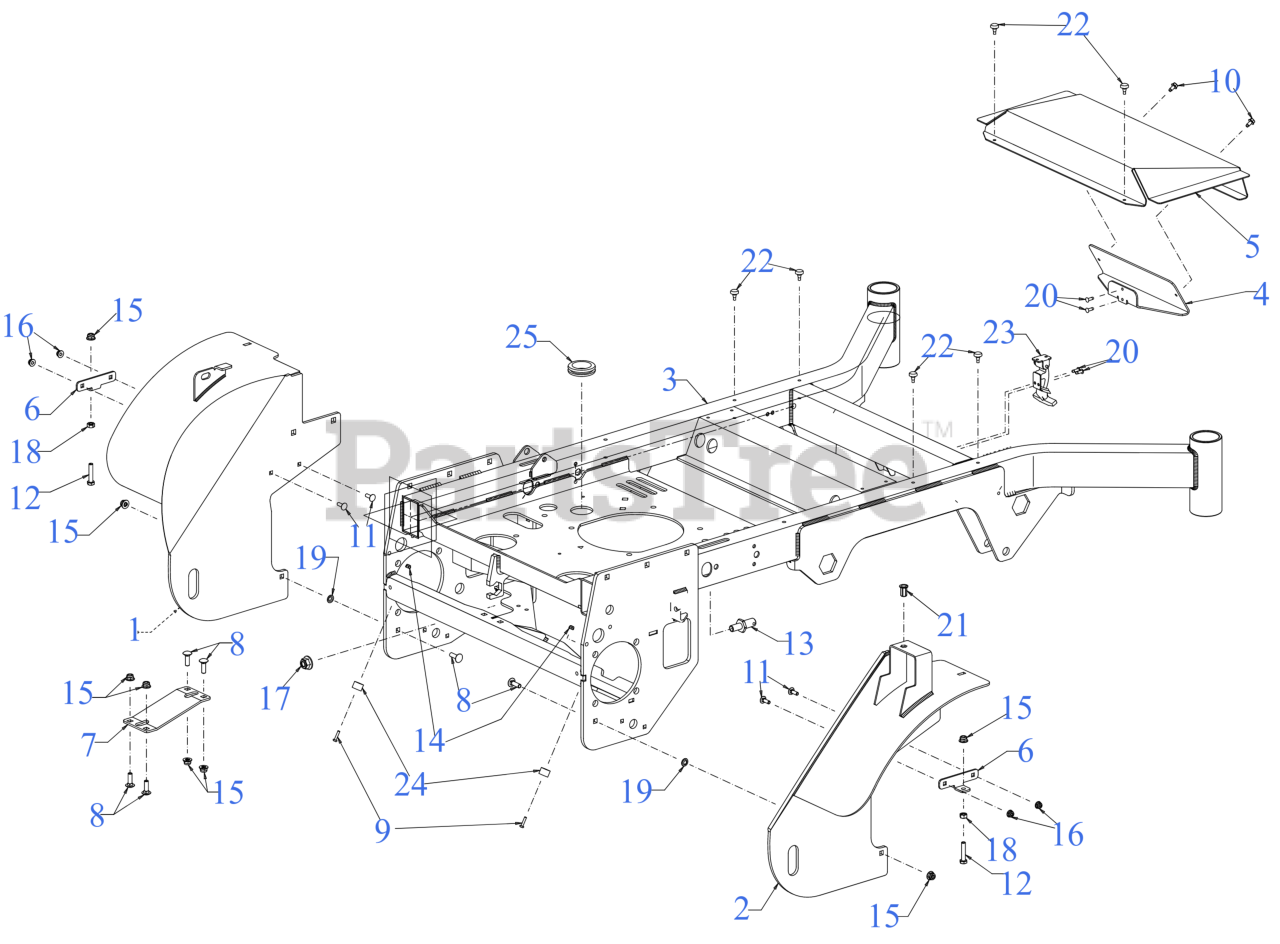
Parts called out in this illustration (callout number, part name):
1	FENDER (LH)
2	FENDER (RH)
3	60" FRAME
4	BACK PLATE
5	FRONT COVER
6	BRAKE SPRING BRACKET (RH)
7	SUPPORT BRACKET
8	CARRIAGE BOLT 5/16-18 x 1.00
9	SCREW #8-32 x .750
10	SCREW 1/4-20 X.500
11	SCREW 1/4-20 x .75 GR5
12	SCREW 5/16-18 x 1.5 LG
15	FLANGE LOCK NUT 5/16-18
16	FLANGE LOCK NUT
18	HEX NUT 5/16-18
20	POP RIVET
21	RIV NUT 3/8-16
22	RUBBER BUMPER
23	HOOD LATCH ASSEMBLY
24	RUBBER BUMPER
25	RUBBER GROMMET (1.50X2.13X.563)
